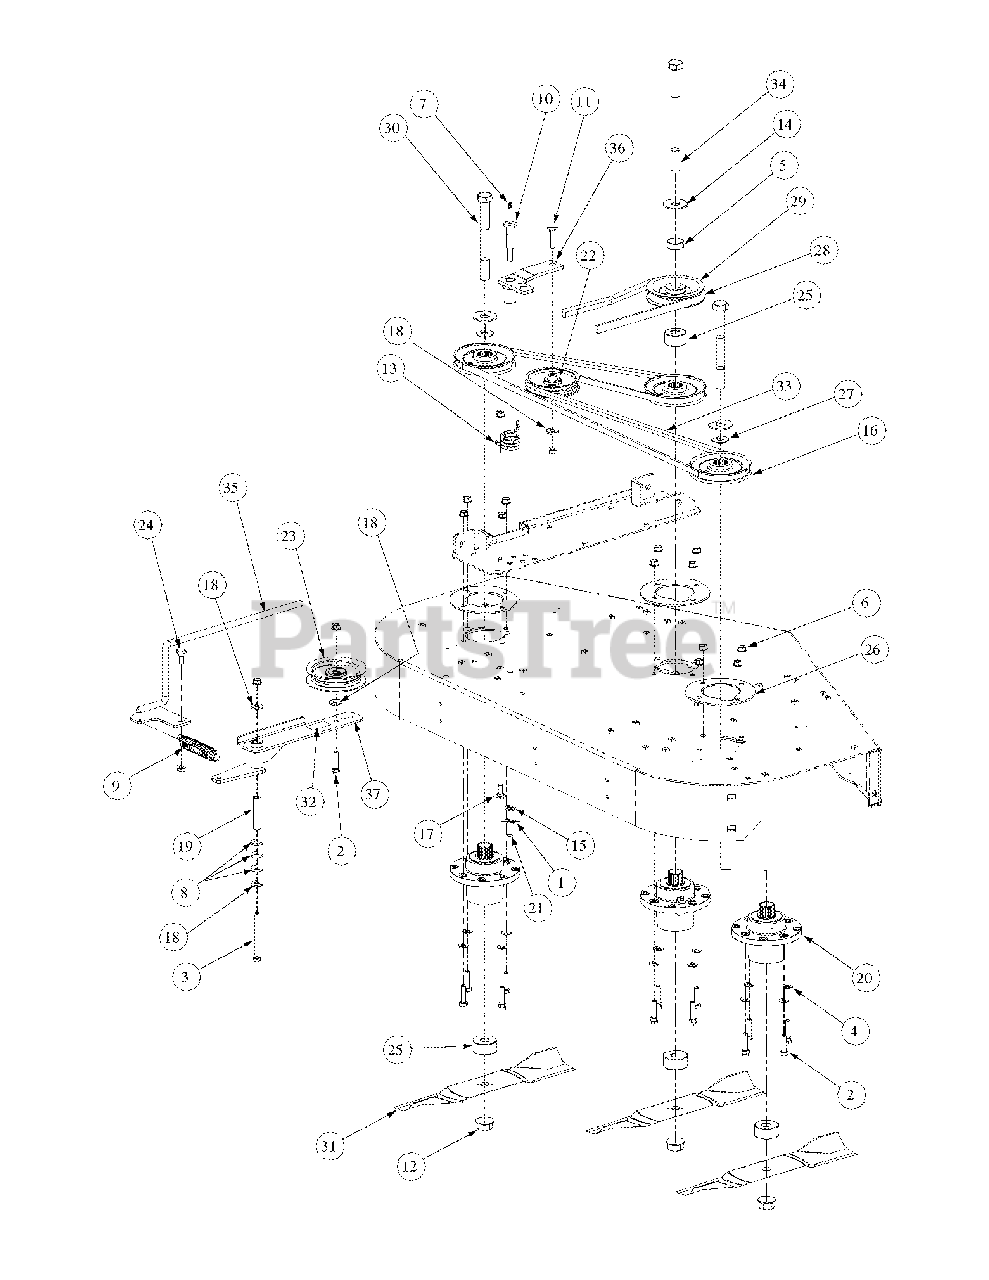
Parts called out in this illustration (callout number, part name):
1	Lock Washer, 7/16
2	Hex Cap Screw, 3/8-16 x 1-1/4
3	Hex Cap Screw, 3/8-16, 4.00
4	Flat Washer, 3/8
6	Hex Nut, Flange Lock, 3/8-16
7	Grease Fitting, 1/4-28 x 3/16
8	Idler Washer
9	Spring Extension, 1.0 OD x 5.125
10	Shoulder Screw, 7/16-14
11	Hex Carriage Screw, 3/8-16, 1.75
12	Hex Flange Nut, 3/4-16
13	Torsion Idler Spring
14	Flat Washer, .781 ID, 2.00 OD, .105
15	Flat Washer, .469 ID, .875 OD, .105
16	V-Pulley, 5.00 OD
17	Carriage Bolt, 3/8-16 x 1
18	Flat Washer, .406 ID, 1.0 OD, .105
19	Spacer, .39 ID x .625 OD x 2.75
20	Aluminum Spindle Assembly
21	Hex Nut, 7/16-14
22	Flat Pulley
23	Idler Pulley, 4.06 OD w/Deep Flange
24	Shoulder Screw, .50 x .27 Lg., 3/8-16
25	Spacer, .760 ID x 2.000 OD x 1.1
26	Spindle, Aluminum Cast Support Plate
27	Spacer, .812 ID x .218 LG
28	V-Belt, B Section x 83.2
29	V-Pulley, 4.75 OD
30	Hex Cap Screw, 3/4-16, 7.00
31	Blade, 17.0, Hi-Lift, 0.756 ID
32	Decal, Idler Location
33	V-Belt, A Section x 105.3
34	Hex Cap Screw, 3/4-16, 9.00
35	Spring Tension Rod Assembly
36	Idler Arm Assembly, Deck Spindle
37	Idler Arm Assembly, Flat Top Bearing
